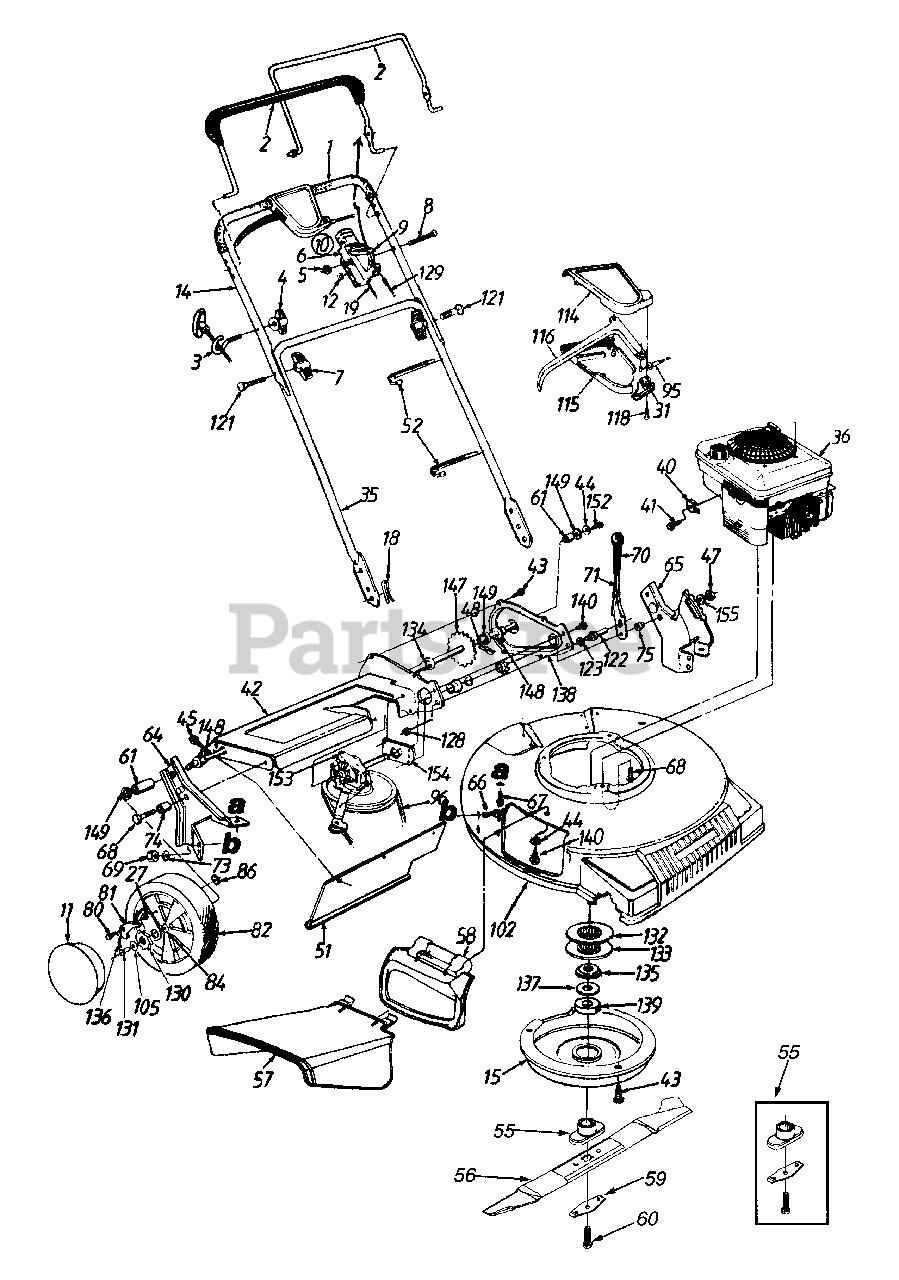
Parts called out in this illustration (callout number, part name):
1	Grip
2	Control Handle w/Plastic
3	Rope Guide
4	Handle Knob 1/4-20Thd.
5	Hex L-Nut 1/4-20 Thd.
6	Throttle Body
7	Hand Knob
8	Oval C-Sunk Scr.
9	Throttle Lever
10	Throttle Box Comp.
11	Hub Cap
12	Spr. Wash. .66" I.D.
19	Throttle Control Wire 55" Lg.
27	Pawl Plate
31	S.R Control Cover
36	Engine
40	Cable Clamp
41	Hex Self-Tap Scr. #10-32 x .62"
44	Bell-Wash. 1/4" I.D.
45	Hex AB-Tap Scr. 1/4 x .62"
47	Hex Patch L-Nut 3/8-24 Thd.
48	#48 Chain .500" Pitch x 38 Links
51	Rear Flap 4.8" x 17.5" Lg.
52	Cable Tie
55	Blade Adapter
56	21" Mulching Blade
57	Chute Ass'y.
58	Mulching Plug Ass'y.
59	Blade Bell Support
60	Hex Bolt 3/8-24 x 2.5"
61	Spacer .513" I.D.
67	Hex B-Tap Scr. 5/16-18
68	Hex TT-Tap Scr. 3/8-16
69	Hex Nut 5/16-18 Thd.
71	Height Adj. Lever
73	Bell-Wash. 5/16" I.D.
74	Spacer .383" I.D.
75	Shld. Spacer.5" Dia.
80	Shld. Scr. .342" Dia. x .268
81	Pawl-R.H.
82	Wheel Ass'y. Comp.- Rear
84	Sleeve Bearing 1/2" I.D.
86	Weld Top L-Nut 1/4-20 Thd.
95	S.P. Cable-44" Lg.
96	'V'-Belt
114	Self-Propelled Control Cover
115	Self-Propelled Control Cover
116	Control Lever
118	Fl-'C'-Sunk Hd. Tap Scr. 10 x .75" Lg
121	Curved Hd. Bolt 5/16-18 x 2" Lg.
122	Shld. Pin 1.43" Lg.
123	L-Wash. 3/8" I.D.
128	Hex Jam Nut 3/8-24 Thd.
129	Control Cable-39"
130	Ratchet Wheel 1.62" O.D.
131	Cap Screw HH 1/4-20 x .620
132	Pulley Half
133	Pulley Half
135	Spr. Wash. .89" I.D.
136	Spring-Nylon
137	Fl-Wash. .85" I.D.
140	Hex S-Tap Scr. 1/4-20 x .50"
147	Rear Shaft Ass'y. 21.44" Lg.
148	Hex Flange Brg..506" I.D.
149	Fl-Wash. .531" I.D. x .930"
152	Hex Bolt 1/4-20 x .62" Lg. (Grade 5)
153	Transmission Comp.
155	Fl-Wash. .385" I.D. x .87" O.D.
